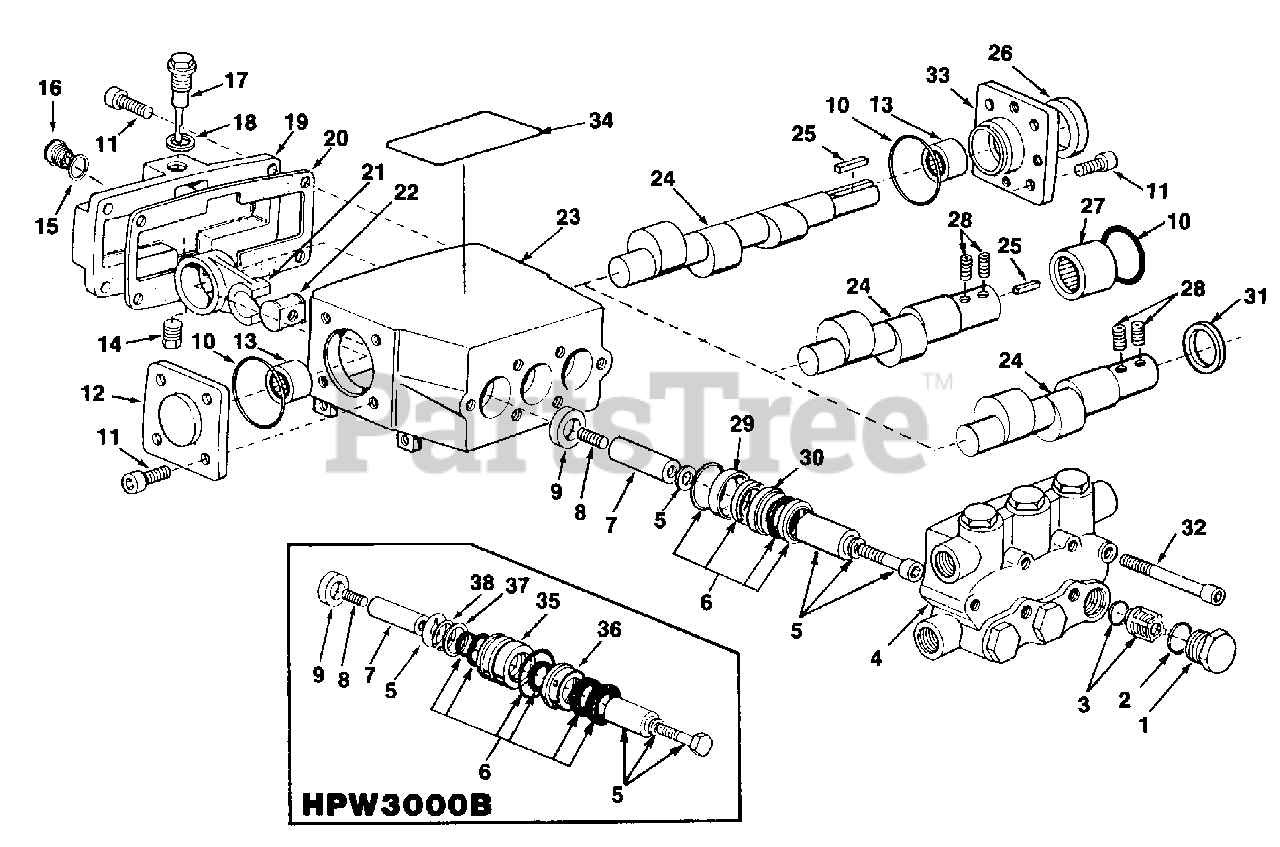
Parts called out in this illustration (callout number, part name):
4	HEAD (HPW2000R) TBO
24	CRANKSHAFT
26	SHAFT SEAL TBO
32	SOC HD SCREW
